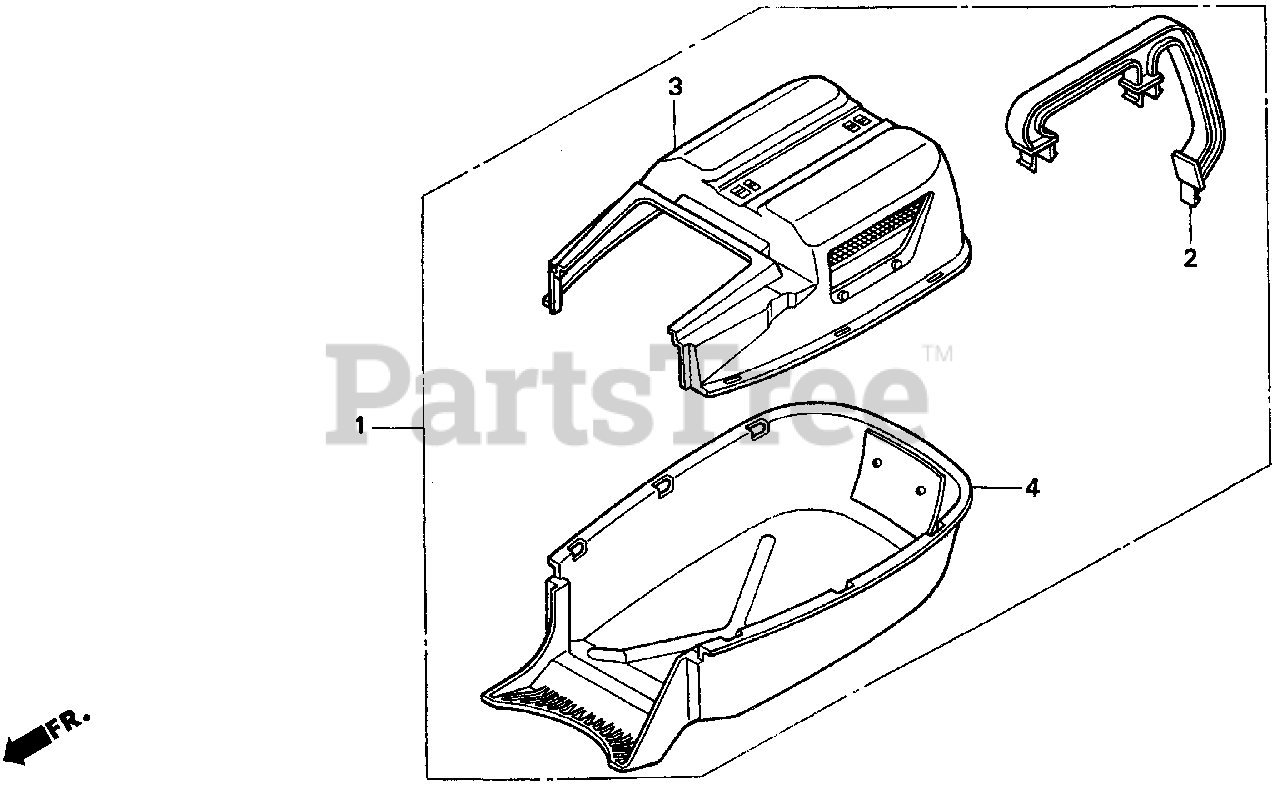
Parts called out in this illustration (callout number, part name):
1	CATCHER KIT, GRASS
2	HANDLE, GRASS CATCHER
3	CATCHER, GRASS (UPPER)
4	CATCHER, GRASS (LOWER)
